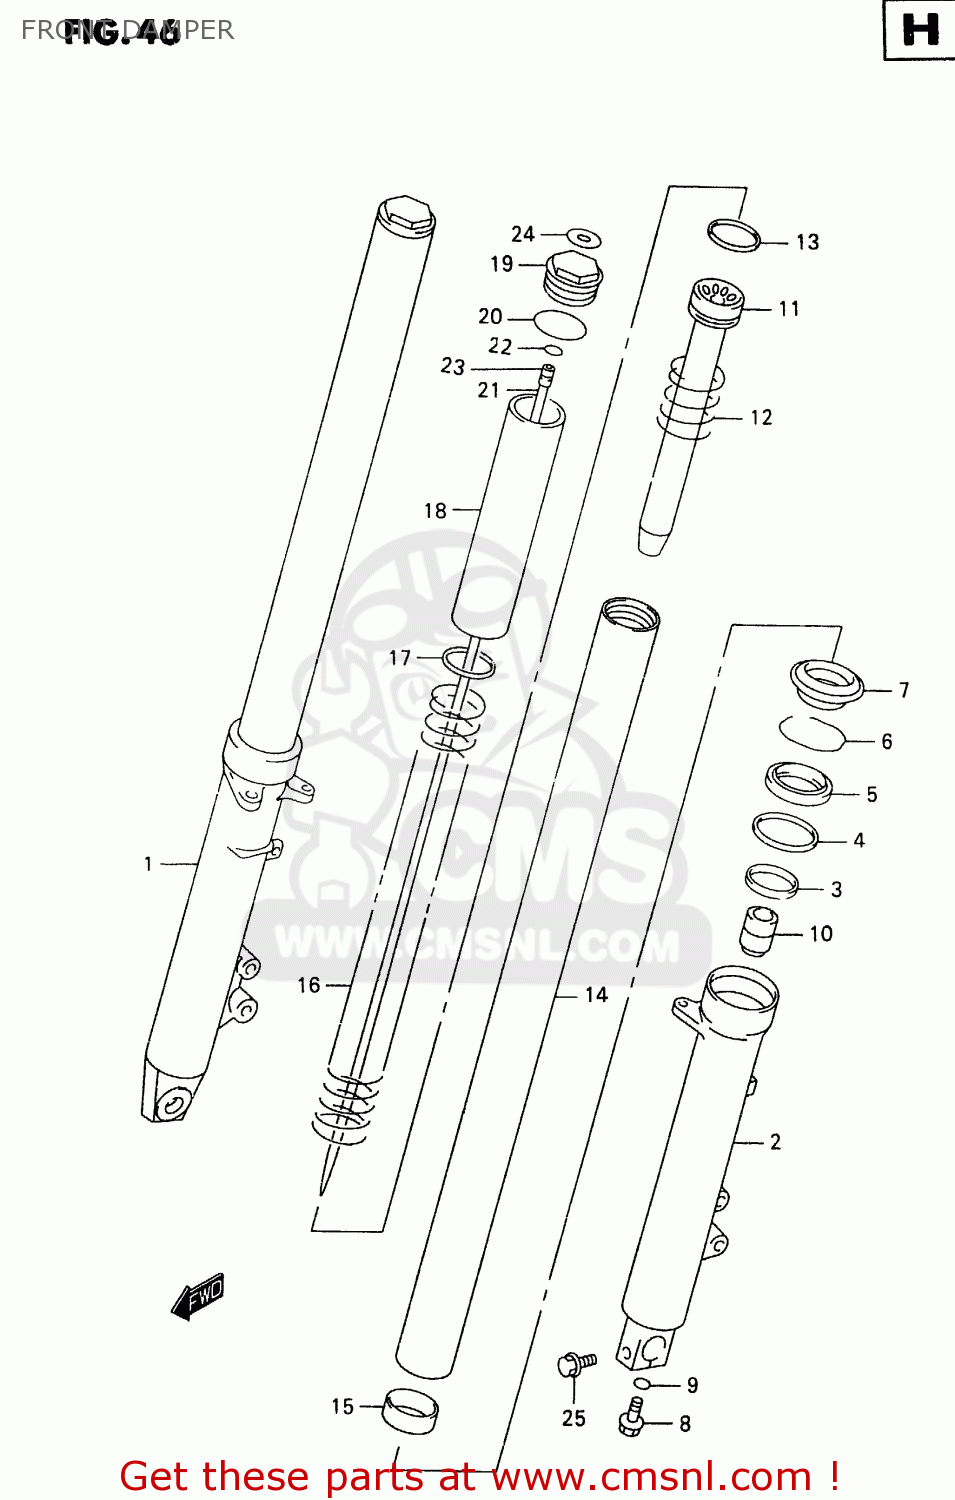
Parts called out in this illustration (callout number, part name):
1	TUBE,OUTER,R
2	TUBE,OUTER,L
3	BUSH,GUIDE
4	SPACER,SEAL
5	SEAL,OIL
6	CIRCLIP,FORK OIL SEAL
7	SEAL,DUST
8	BOLT(8X27)
9	GASKET (NAS)
10	PIECE,OIL LOCK
11	SEAT,UNDER
12	SPRING,REBOUND
13	RING,PISTON
14	TUBE,INNER
15	BUSH,SLIDE
16	SPRING,FR
17	JOINT,SPRING
18	SPACER,SPRING
19	BOLT,FORK
20	O RING
21	ROD,DAMPER
22	O RING(D:1.9,ID:5.7)
23	RING,STOPPER(ID:6.1,D:0.6)
24	LABEL,S-H
25	BOLT
